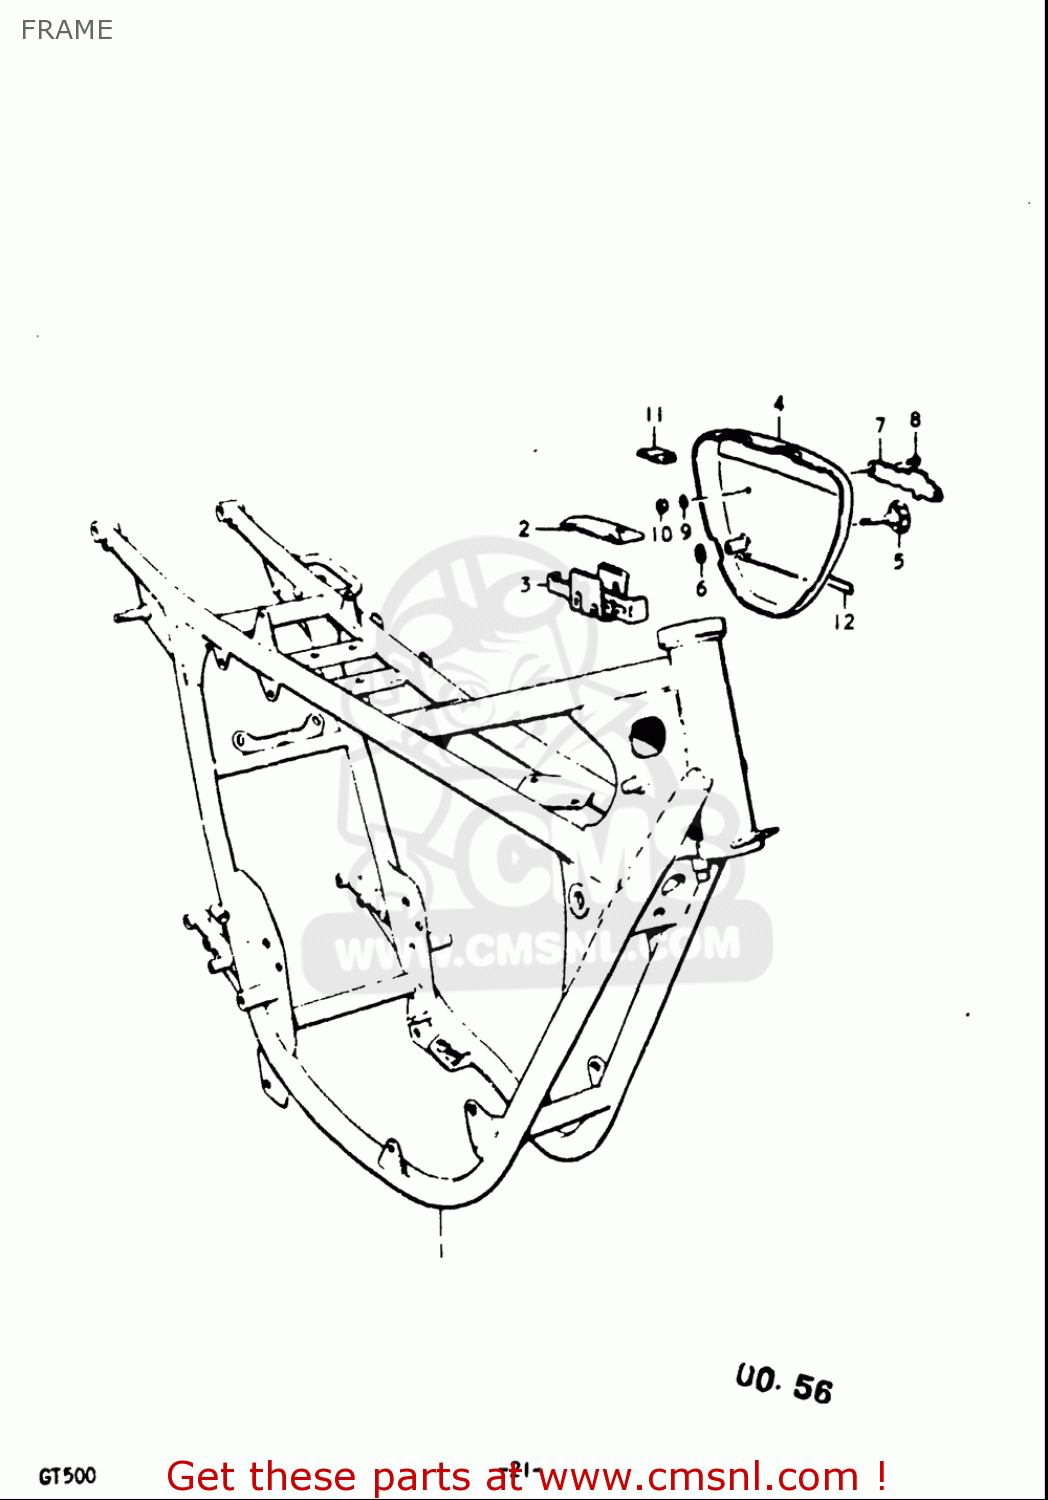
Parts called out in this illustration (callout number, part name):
2	TOOL ASSY
5	KNOB,FRAME COVER,L
6	NUT
9	WASHER,LOCK
10	NUT
